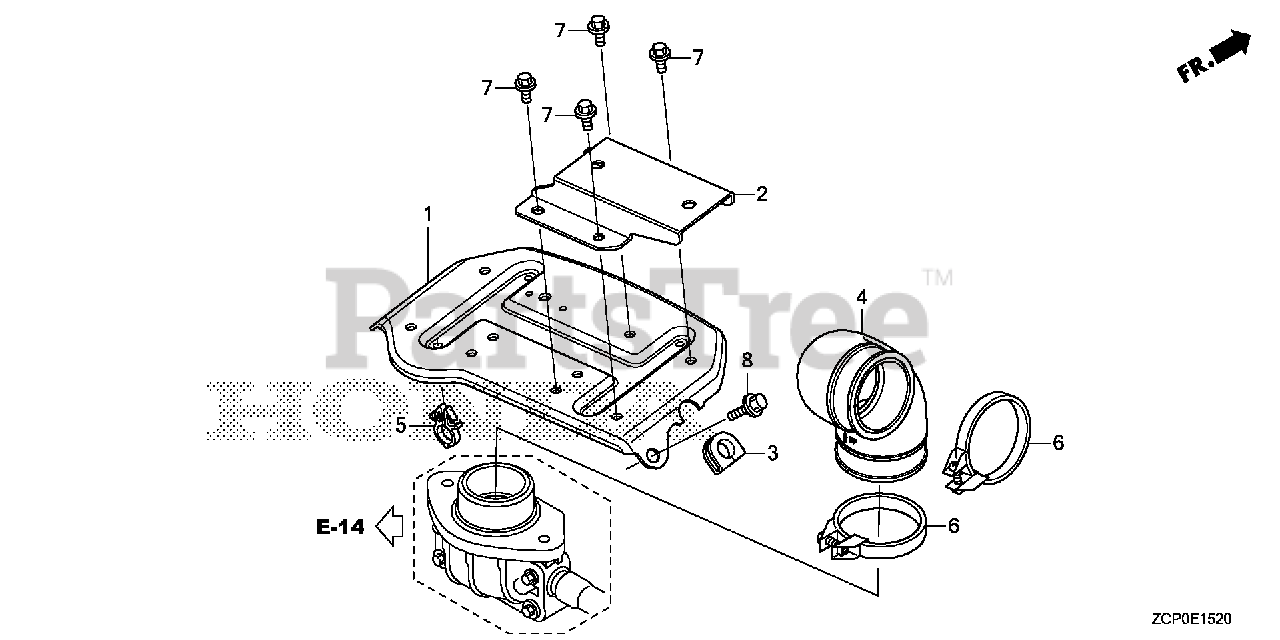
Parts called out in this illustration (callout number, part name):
1	STAY, AIR CLEANER
2	SUB-STAY, AIR CLEANER
3	GROMMET, AIR CLEANER STAY
4	TUBE, AIR CLEANER CONNECTING
5	CLIP, WIRE HARNESS
6	BAND, AIR CLEANER CONNECTING TUBE (58)
7	BOLT, FLANGE (6X12)
8	BOLT, FLANGE (8X16)
